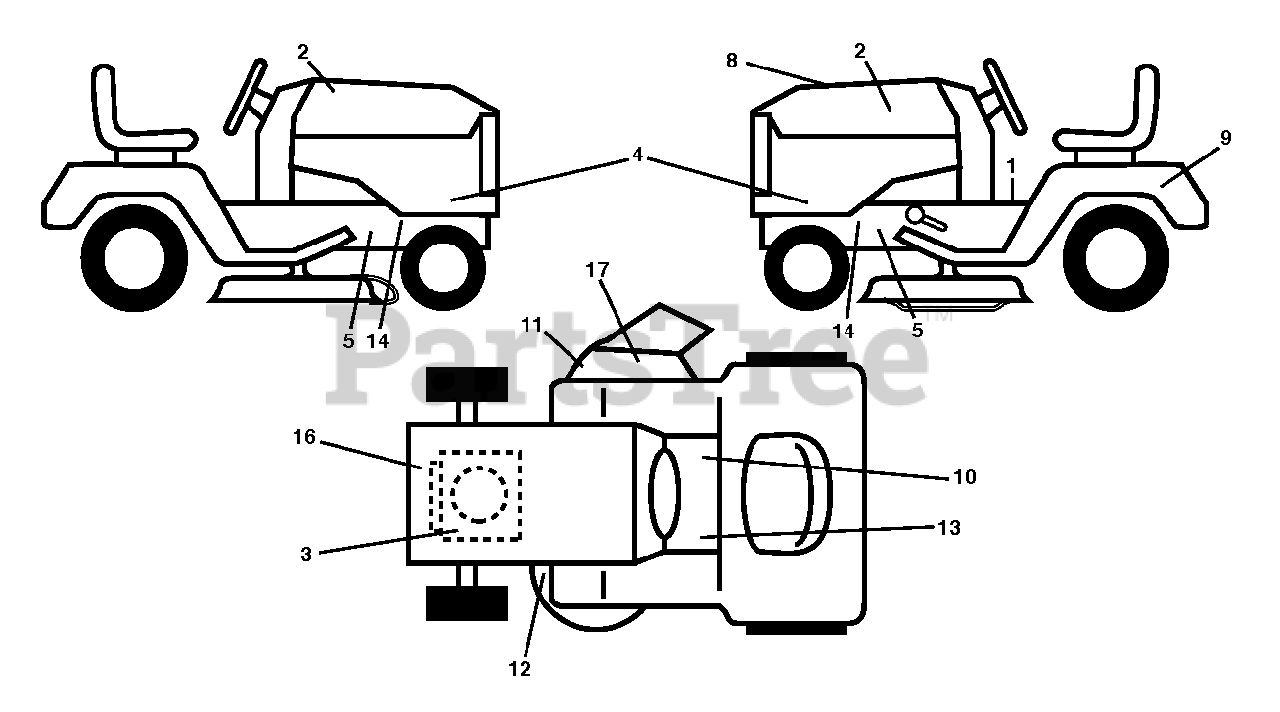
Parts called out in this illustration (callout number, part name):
1	DECAL.READ.OWN.MAN.SYMBOL.LT
2	DECAL.BADGE.170MM.TEXTLOGO.
3	DECAL.ENGINE.WARNING
4	DECAL.SDPNL.TS38
5	DECAL.CHASSIS.HOT.MUFFLER
8	DECAL.RPL.BSM21.PB.TLW.38.PMST
9	DECAL BTRY SYMBOLS
10	DECAL.PARKING.BRAKE.SADDLE.LT
11	DECAL.DFLCTR.WARNNG.CTFNGR.SYM
12	DECAL.DECK.SCH.36,38,94.NONCR
13	DECAL.FNDR.SDLE.BRAKE.CLUTCH.6
14	DECAL.WARNING.SERVCE/FIRE
16	DECAL.ENG.BS.3125SER.PB.279738
17	DECAL, DECK DEFLECTOR, WARNING
